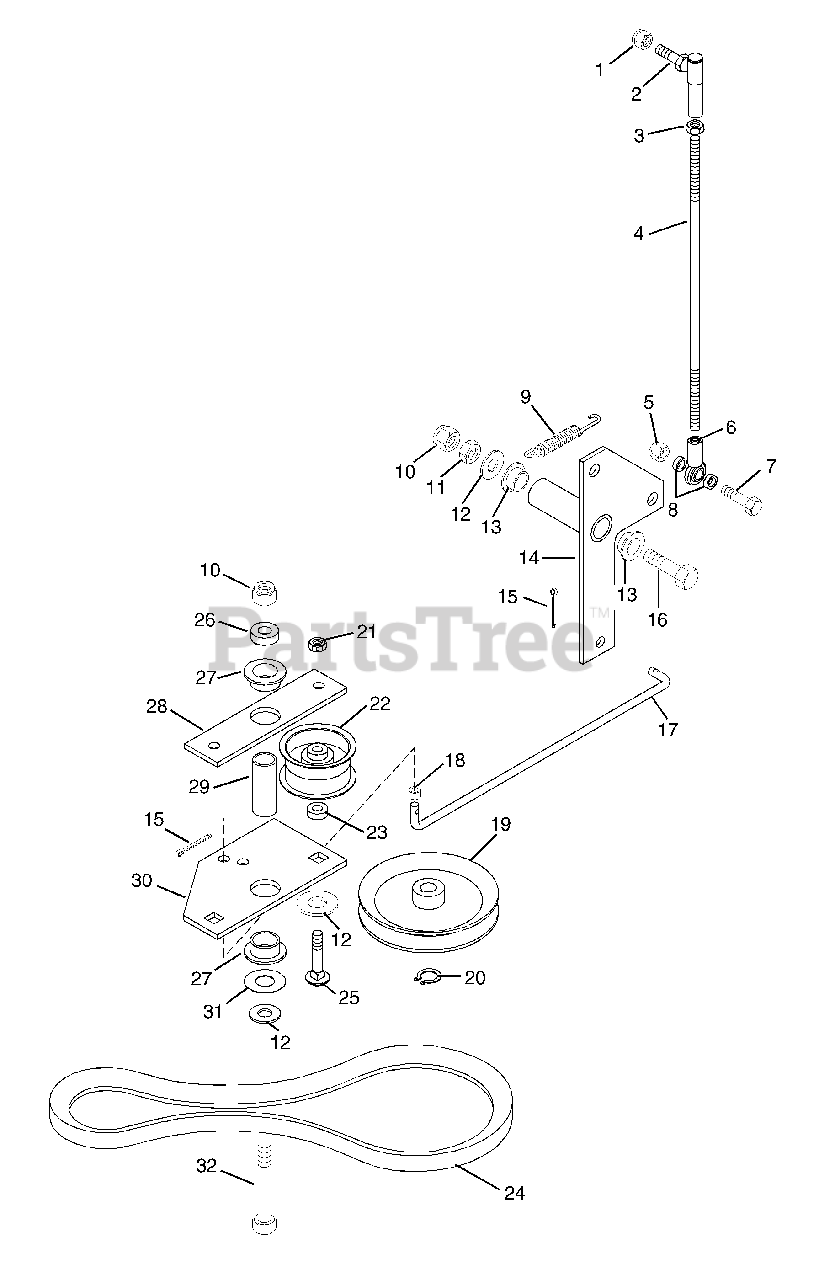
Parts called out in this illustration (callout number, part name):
1	Nut-Locking-Nylon .375-24
2	Joint, Steering Ball
3	Nut-Hex .375-24
4	Rod, Clutch Actuating
5	Nut-Locking-Nylon .375-16
6	Rod End, Spherical Bearing
7	Bolt-Hex .38-16 x 1.50 Grade 5
8	Bushing-Flange .383 x .50 x .165
9	Spring-Tension .095 x .500 x 5.5
10	Nut-Locking-Nylon .50-13
11	Nut .50-13
12	Washer-Flat-Steel .531 x 1.06 x .095
13	Bushing-Flange .515 x .750 x .745 x 1.00
14	Weldment, Clutch Arm
15	Pin-Cotter .09 x .75
16	Bolt-Hex .50-13 x 4.50
17	Rod, Traction Clutch
18	Bushing, Steel .380 x .495 x .437
19	Sheave, Transmission
20	Ring-Retaining-External .579 x .93
21	Nut-Locking-Center .625-10
22	Idler-Flat 2.468 x .38
23	Bushing .406 x .750 x .188
24	V-Belt A-Section
25	Bolt-Round Head Square Neck .38-16 x 1.75
26	Bushing, Steel .790 x 1.00 x .320
27	Bushing-Flange .762 x 1.0 x .580 x 1.48
28	Plate, Idler
29	Bushing, Steel .560 x .745 x 2.04
30	Plate, Idler
31	Bearing-Needle-Thrust .752 x 1.24 x .093
32	Bolt-Hex .50-13 x 3.00
